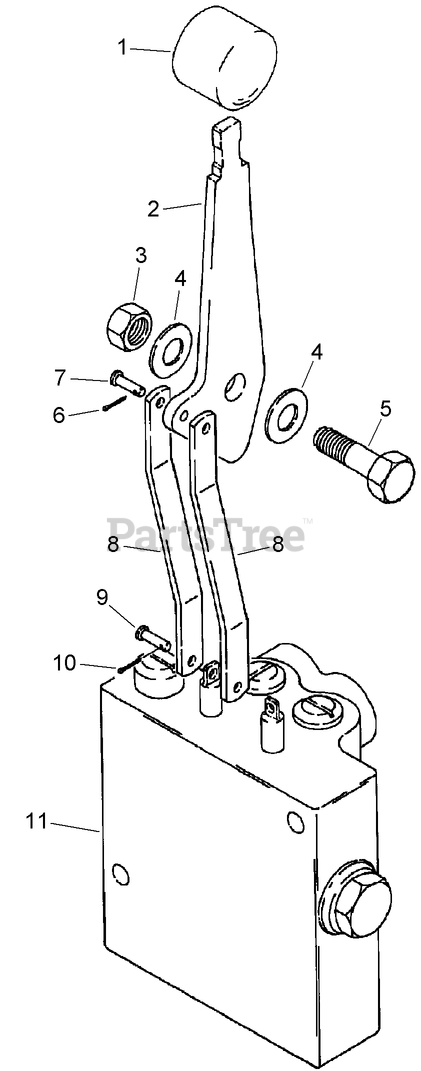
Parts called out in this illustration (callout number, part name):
1	KNOB-GREEN
2	HANDLE - Control, Attachment Lift
3	NUT-JAM
4	WASHER-0.531 x 1.062 x 0.092 in CST ZND
5	SCREW-HH
6	PIN - Cotter .062 x .50 in ZND
7	PIN-CLEVIS
8	LINK - Control Valve
9	PIN-CLEVIS
10	PIN - Cotter .062 x .50 in ZND
11	HYD STEERING VALVE ASM
